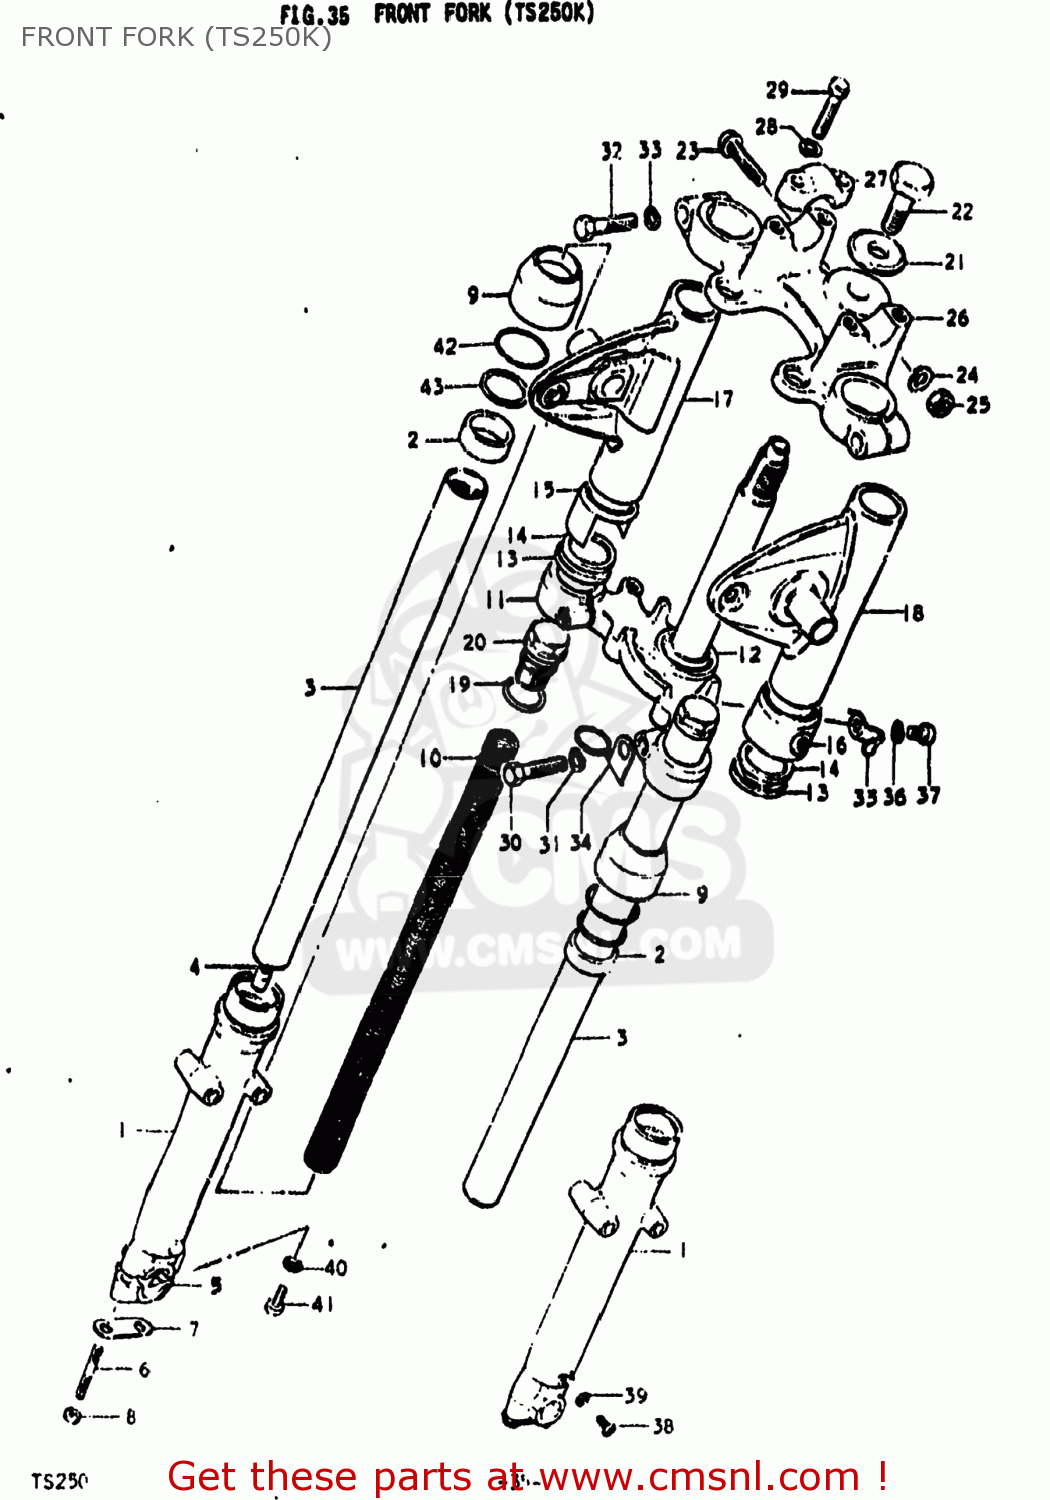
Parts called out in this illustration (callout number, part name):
1	TUBE,OUTER,RIGHT
2	SEAL,OIL
3	TUBE,FORK,INNER
4	CYLINDER,FRONT FORK
5	HOLDER,AXLE
6	STUD BOLT
8	NUT
9	DUST SEAL,FRONT FORK
10	SPRING,FRONT FORK
11	STEM,STEERING
12	LACE,STEERING OUTER
13	GUIDE, COVER
14	CUSHION,HEADLAMP BRACKET
15	CUSHION,HEADLAMP BRACKET
17	BRACKET,HEADLAMP HOUSING
18	BRACKET,HEADLAMP,LEFT
19	O RING
20	CAP,FORK INNER TUBE
21	WASHER
22	WASHER
23	BOLT,FORK INNER TUBE F
24	LOCK WASHER
25	NUT
26	HEAD,STEERING STEM
27	HOLDER,HANDLEBAR
28	LOCK WASHER
29	BOLT
30	BOLT,FORK INNER TUBE F
31	WASHER,LOCK 12
32	BOLT,FORK INNER TUBE F
33	LOCK WASHER
34	GUIDE,CABLE
35	CLIP
36	LOCK WASHER
37	SCREW
38	SCREW
39	GASKET,DRAIN,PLUG (NAS)
40	GASKET (NAS)
41	BOLT,FORK CYLINDER(10X25)
42	RING,OIL SEAL STOPPER
43	WASHER
